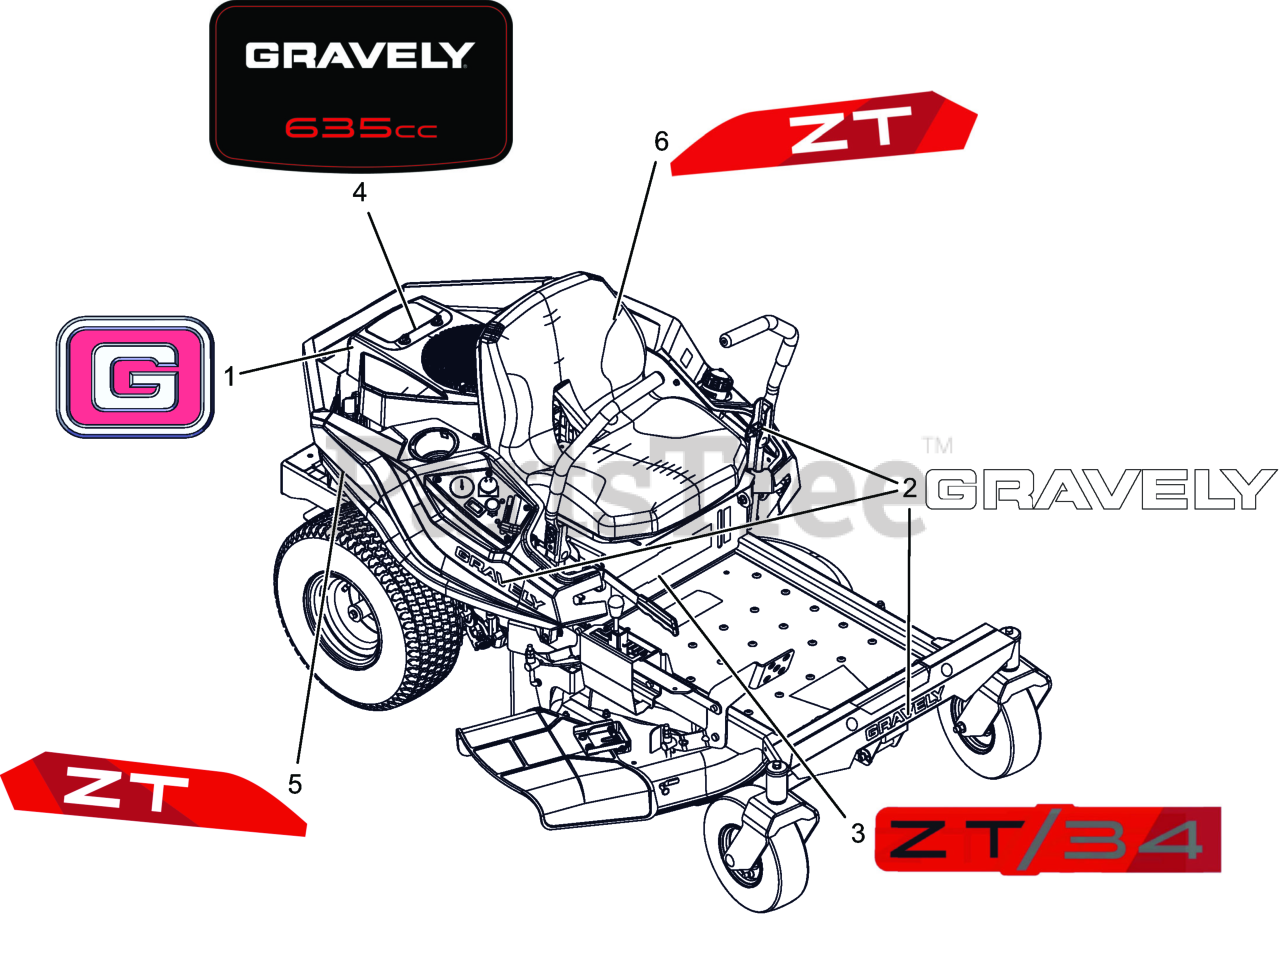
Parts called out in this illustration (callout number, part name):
1	DECAL, GRAVELY BRAND
2	DECAL, 9.5" GRAVELY LOGO
3	DECAL, GRAVELY ZT / 34
4	DECAL, ENGINE 635CC
5	DECAL, ZT RH FENDER
6	DECAL, ZT LH FENDER
